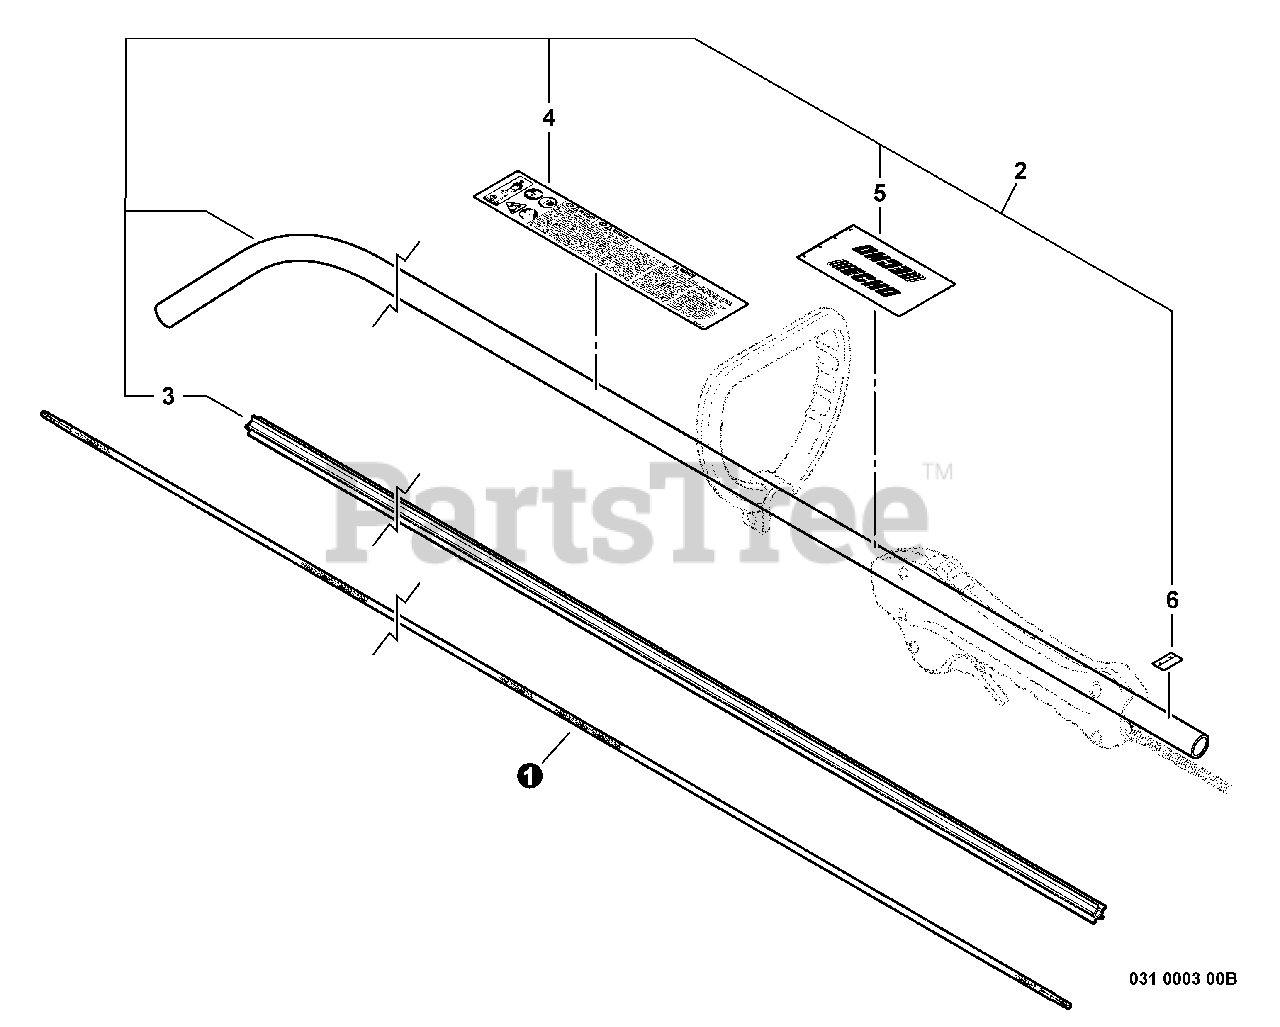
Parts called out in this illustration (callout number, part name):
1	DRIVESHAFT - FLEXIBLE
2	MAIN PIPE ASSY
3	LINER - FLEXIBLE
4	LABEL - CAUTION -- SPANISH
5	LABEL - HANDLE LOCATION
6	LABEL - ALIGNMENT
